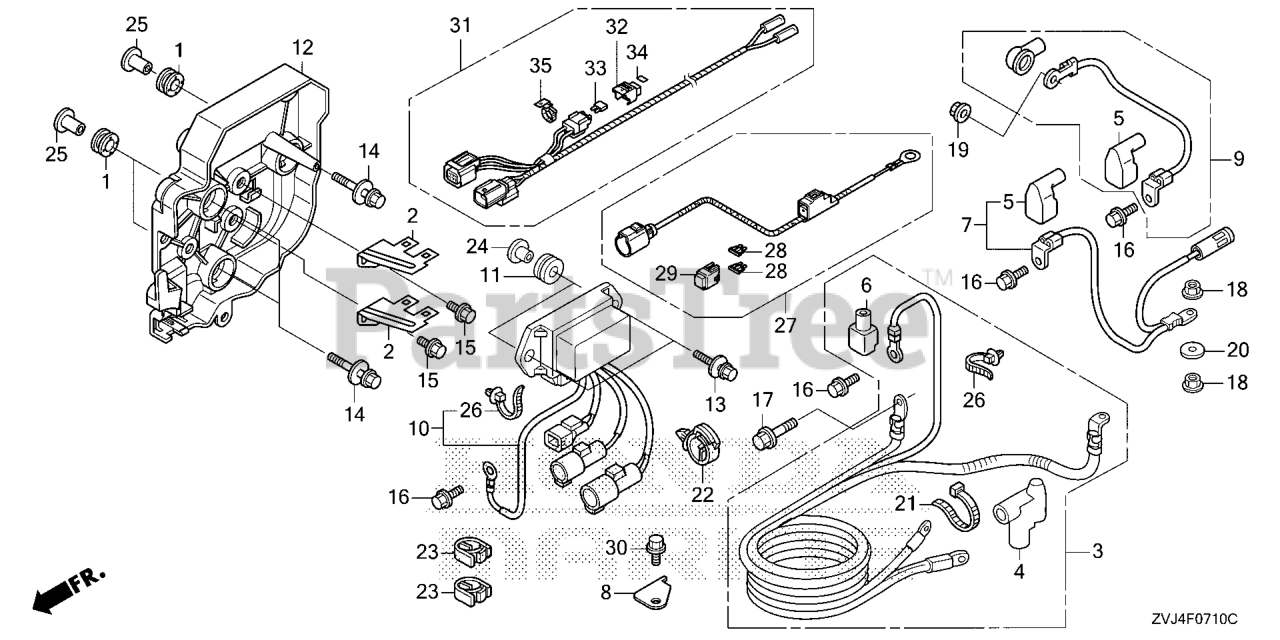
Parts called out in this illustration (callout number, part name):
1	GROMMET, ELECTRONIC PARTS CASE
2	BRACKET, CONNECTOR C
3	CABLE ASSY., STARTER
4	COVER, STARTER TERMINAL
5	COVER B, TERMINAL (L)
6	COVER B, TERMINAL
7	CABLE ASSY., POWER TILT RELAY
8	PLATE, STARTER CABLE
9	WIRE, ALTERNATOR
10	RELAY ASSY., POWER TILT
11	GROMMET, RELAY
12	CASE, POWER TILT RELAY
13	BOLT-WASHER (6X25)
14	BOLT-WASHER (6X27)
15	BOLT, FLANGE (6X10)
16	BOLT, FLANGE (6X12)
17	BOLT, FLANGE (8X18)
18	NUT-WASHER (8MM)
19	NUT-WASHER (6MM)
20	WASHER, PLAIN (8MM)
21	BAND, WIRE (165MM) (BLACK)
22	CLIP, WIRE HARNESS
23	CLIP, WIRE HARNESS
24	COLLAR, MOUNT (6MM)
25	COLLAR, MODULE IGNITION CONTROL CASE (CDI)
25	COLR, CDI UNIT CASE
25	COLLAR (12X6.5)
26	CLIP, HARNESS BAND (145MM) (BLACK)
27	HARNESS ASSY., POWER
28	FUSE, BLADE (40A)
29	COVER ASSY., FUSE (40A)
30	BOLT, FLANGE (6X12) Use from Frame SN 1005249.
31	HARNESS ASSY., LOAD SIGNAL
32	COVER ASSY., FUSE
33	FUSE, BLADE (1A) (MINI)
34	LABEL, FUSE (1A)
35	HOLDER, CONNECTOR (128.6MM) (NATURAL)
